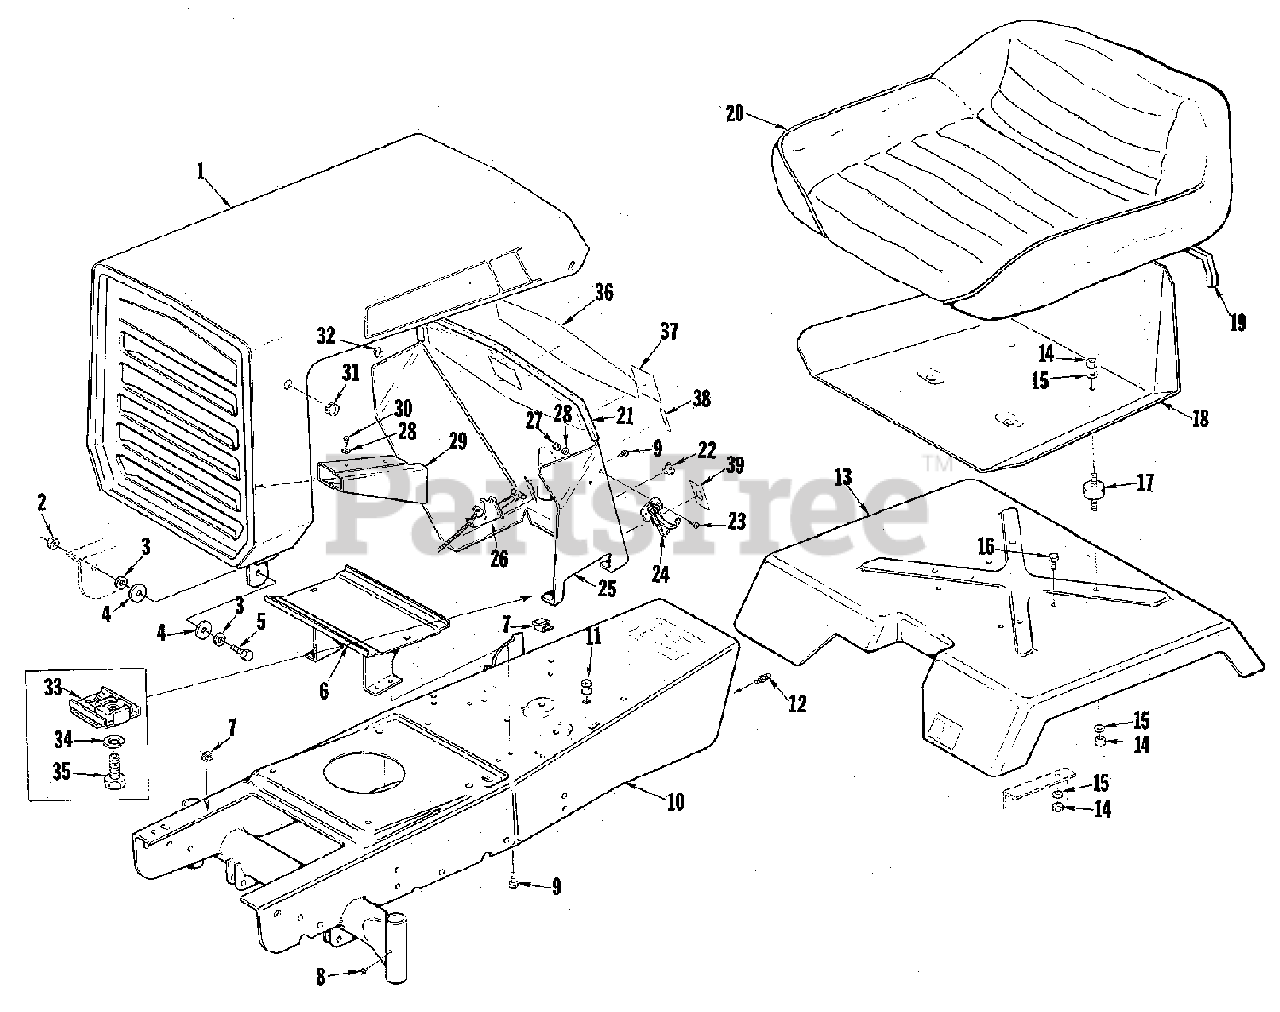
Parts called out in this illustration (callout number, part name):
1	HOOD ASSEMBLY
2	NUT, Hex Lock, 5/16-18
3	WASHER, Flat, 5/16
4	WASHER, Special
5	CAPSCREW, Hex Head, 5/16-18 x 1
6	SUPPORT ASSEMBLY, Battery
8	FITTING, Lube, Straight
9	SCREW, Tap, 1/4-20 x 1/2, Taptite
10	FRAME ASSEMBLY
12	FITTING, Lube
13	SUPPORT, Seat
14	NUT, Hex, 5/16-18
15	LOCKWASHER, 5/16
16	CAPSCREW, Hex Head, 5/16-18 x 3/4
17	CUSHION, Connector
19	TRIM, "U" Channel
21	MOULDING, Dash
22	PLUG, Button
23	SCREW, Machine, 10-24 x 3/8
25	DASH ASSEMBLY
26	CONTROL ASSEMBLY
27	NUT, Hex, 10-24
28	LOCKWASHER, #10 Extension Tooth
29	EXTENSION ASSEMBLY, Exhaust
30	SCREW, Self Tapping, Hex Head, #10 x 3/8
31	PLUG, Button
33	NUT, Retainer
34	LOCKWASHER, Regular, 1/4
35	CAPSCREW, Hex Head, 1/4-20 x 5/8
37	DECAL, Safety Plate
38	DECAL, Throttle
39	DECAL, Key Switch
